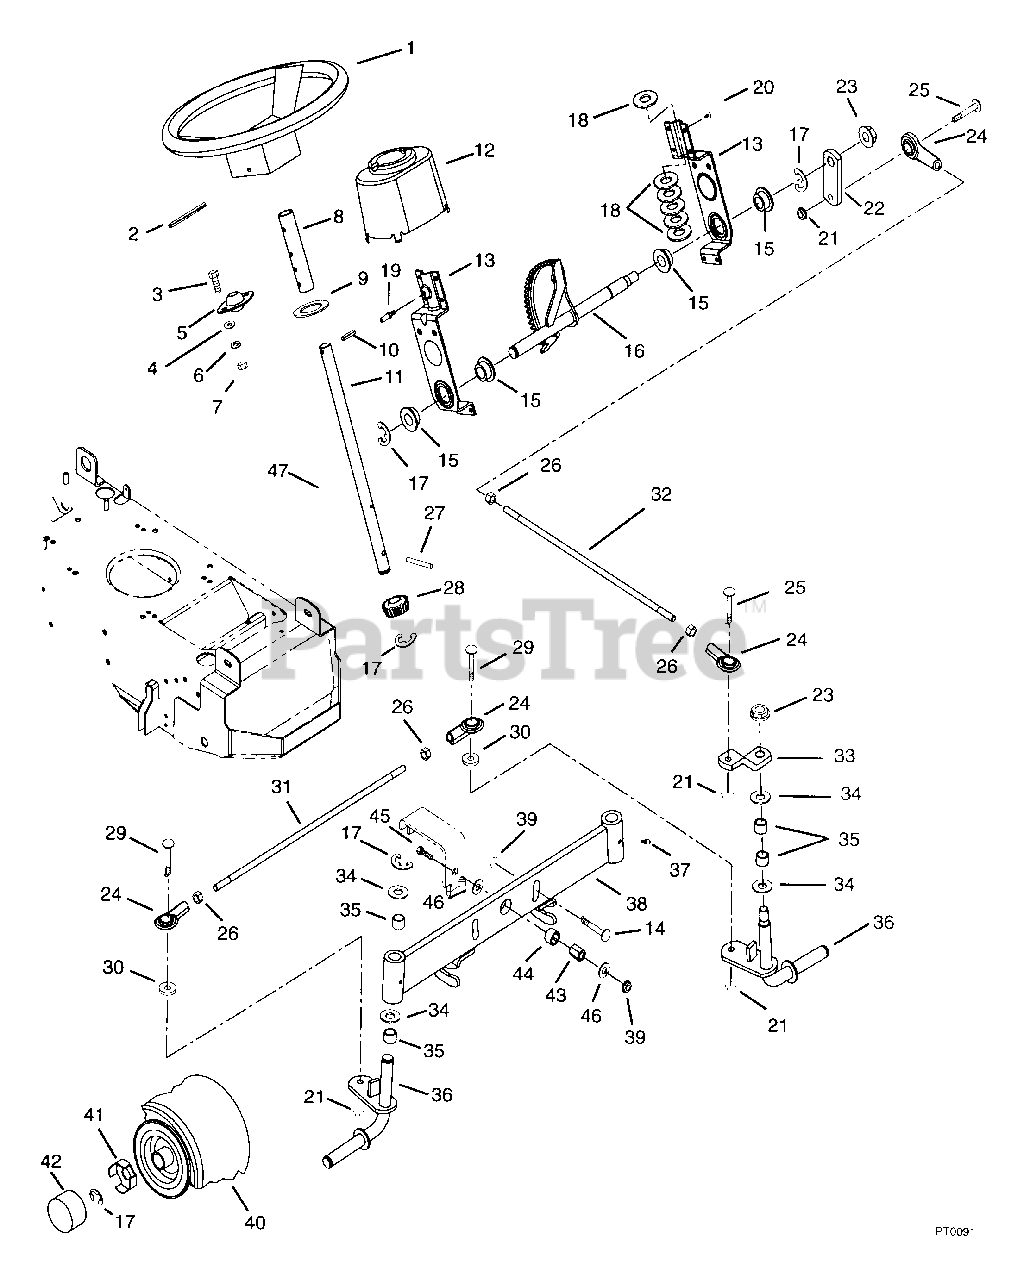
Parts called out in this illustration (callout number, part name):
1	STEERING WHEEL 13"
2	PIN-ROLL .250X1.75
3	BLT-HEX .31-18X.75 PL GR5
4	WSHR-FL-STL.312X.734X.065PL
5	BRG-FLG .751X2 HOLESX.81
6	WSHR-LK .312X.097 PL HVY
7	NUT-HEX .312-18
8	TUBE .754 X .999 X 5.00
9	WSHR-FL-STL .754X1.125X.062 PL
10	PIN-ROLL .250X1.000
11	COLUMN, STEERING
12	CONE- STEERING COLUMN
13	BRACKET, STEERING GEAR
14	BLT-HEX .38-16X1.50 PL GR5
15	BSHG-FLG .750X1.093X.625X1.375
16	GEAR, STEERING
17	RG-RTNG-EXT .750X.050
18	WSHR-FL-STL .755X1.375X.062 PL
19	FTG-LUBE .25-28X.256 YWZC
20	SCR-TAP .250-20X.37 HWH PL TR
21	NUT-LK-CTR .375-16 GR A PL
22	ARM, STEERING ROD
23	NUT-LK .563-18 GR 5
24	ROD END, .38 RH
25	BLT-BTHD .38-16X1.25 GR5
26	NUT .375-24 PL
27	PIN .249X1.125 DRIV-LOK SP
28	PINION GEAR-STEERING
29	BLT-HEX .38-16X1.75 PL GR5
30	BSHG-SLV .377X.624X.370
31	ROD - TIE
32	LINK - DRAG
33	ARM - STEERING SPINDLE
34	WSHR-FL-STL .755X1.375X.093
35	BSHG-SLV .750X.814X .750 BRZ
36	SPINDLE - LH
36	SPINDLE - RH
37	FTG-LUBE .25-28X.256 YWZC
38	AXLE, FRONT
39	NUT-LK-NYL .375-16 PL
40	T/WHL ASSY 15X6.00-6
40	RIM
40	BSHG .75 BORE
40	FTG- LUBE .25-28X.97
41	SPINDLE CUP
42	HUB CAP
43	BSHG-SLV .377X.623X.775 HEX
44	BSHG-SLV .626X1.000X.524 HEX
45	BLT-HEX .38-16X1.75 PL GR5
46	WSHR-FL-STL .390X1.500X.125
47	PIN-ROLL .188X1.13
